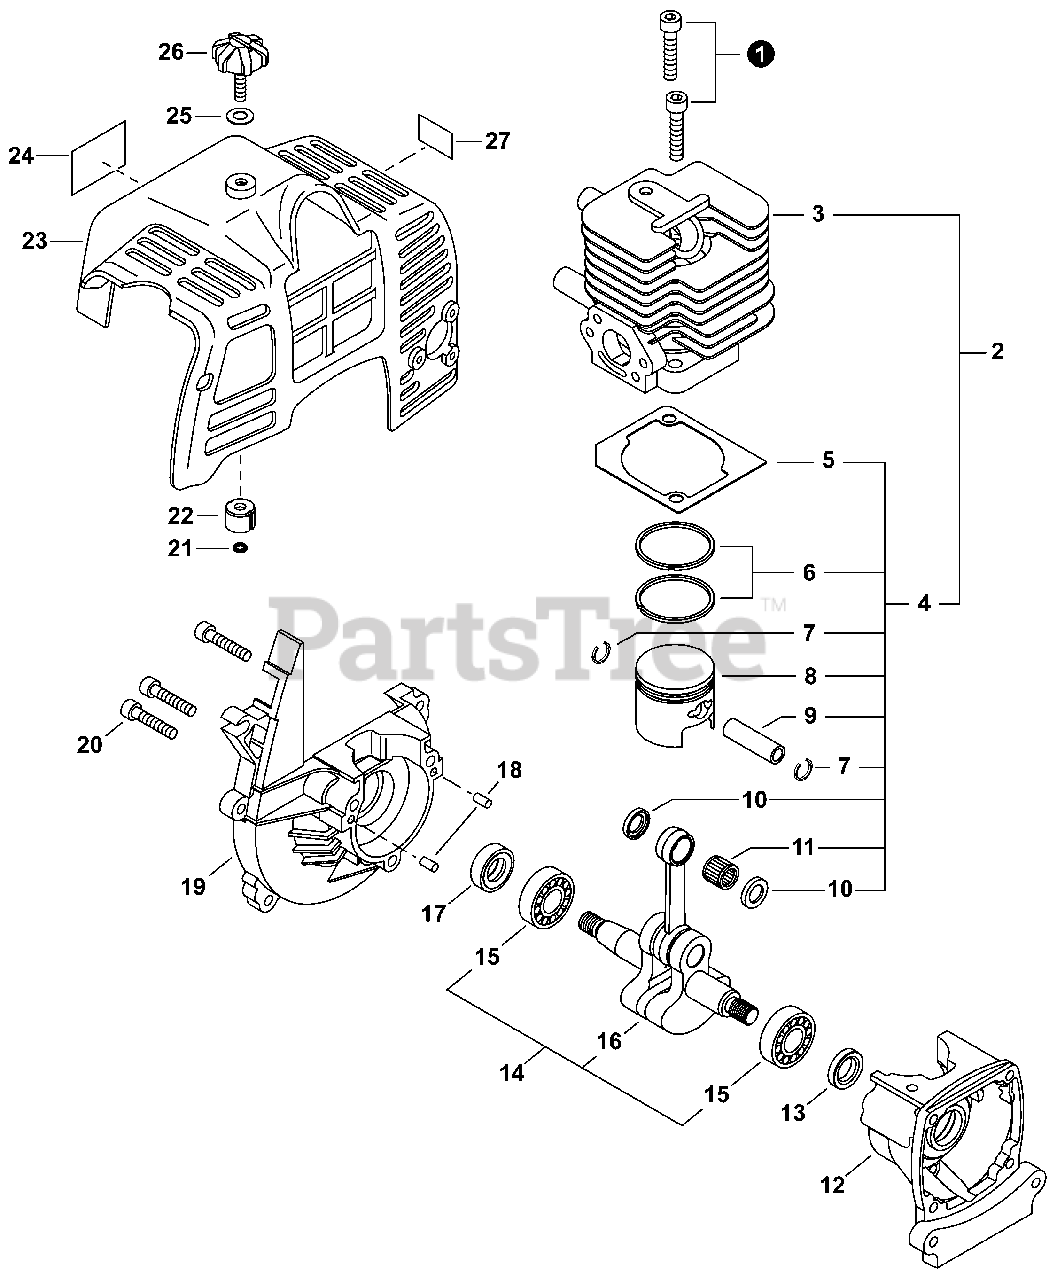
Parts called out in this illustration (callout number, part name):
1	BOLT 5×25
2	REPAIR KIT, ENGINE
3	CYLINDER
4	PISTON KIT
5	GASKET, CYLINDER
6	RING, PISTON
7	RING, SNAP
9	PIN, PISTON 8
10	WASHER, THRUST 8
11	BEARING, NEEDLE 8
12	CRANKCASE S
13	SEAL, OIL 12
14	CRANKSHAFT ASSY
15	BEARING, BALL 6001
16	CRANKSHAFT
17	SEAL, OIL 12
18	PIN, LOCATING 4×8
19	CRANKCASE M
20	BOLT 5×25
22	INSULATOR 5MM
23	COVER, ENGINE
24	LABEL - MODEL T230X
25	WASHER, CONE M6
26	THUMBSCREW
27	LABEL, CAUTION - HOT
